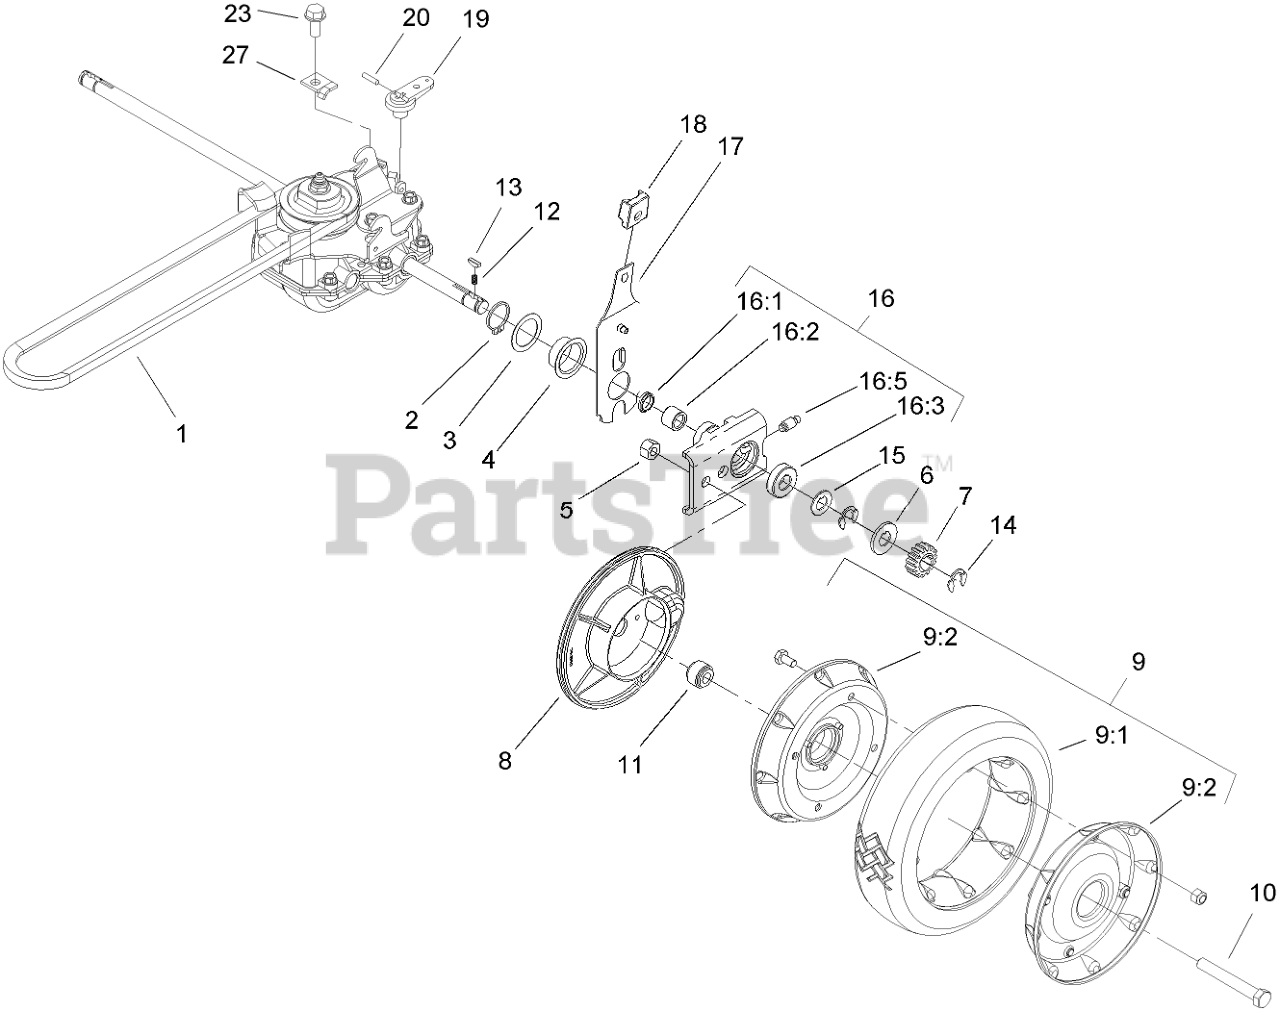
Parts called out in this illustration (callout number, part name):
1	V-BELT
2	RING-RETAINING
3	WASHER
4	CAP-END
5	NUT-LOCK, CONE
6	WASHER-THRUST, OUTER
7	GEAR-PINION
8	COVER-WHEEL
9	Wheel And Tire ASM
9:2	Wheel ASM
10	SCREW-HH
11	SPACER-COVER, WHEEL
12	SPRING-COMPRESSION
14	RING-RETAINING
15	WASHER-THRUST, OUTER
16	PIVOT ARM ASM
16:1	SEAL-OIL
16:2	BEARING-ROLLER
16:3	BEARING-WHEEL
17	REAR SPRING ARM ASM
18	KNOB-ARM
19	LEVER-SHIFT
20	PIN-COIL
23	SCREW-HWHTF
27	CLAMP-CABLE
